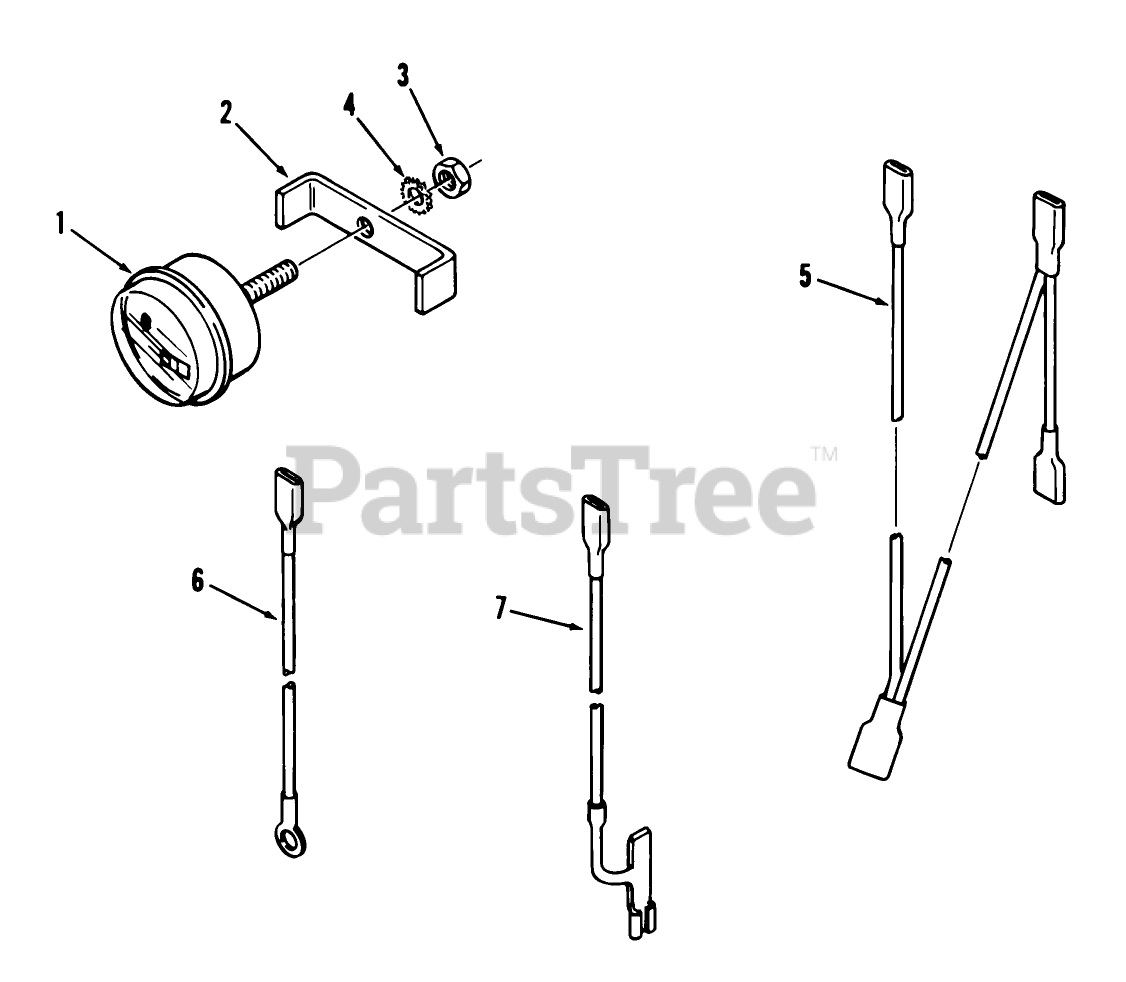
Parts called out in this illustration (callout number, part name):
1	Hour Meter
2	Clamp
3	Nut
4	LOCKWASHER
5	Assy-Wire Gauge
6	SY WIRE HR METER G
7	Wire Assy
